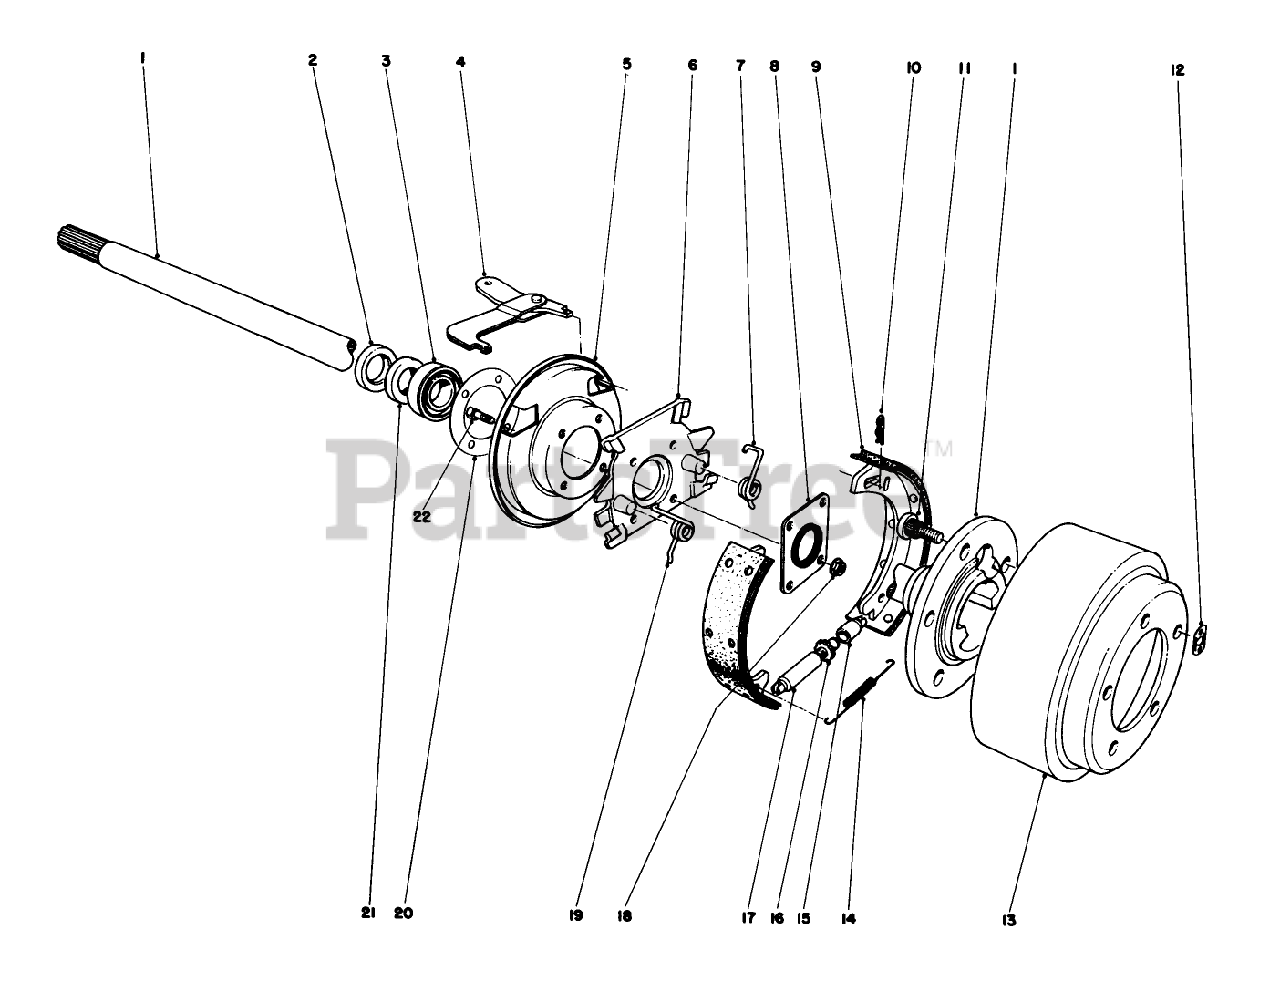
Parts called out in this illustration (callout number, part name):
1	SHAFT-AXLE, FLANGED
2	Oil Seal
3	BEARING ASM
4	STRUT AND LEVER ASM
5	SHIELD-DUST
6	SPIDER-TORQUE
7	SPRING-RETURN, RH
8	SEAL-GREASE
9	Assy.-Shoe & Lining
10	RETAINER-LEVER, BRAKE
11	STUD-DRIVE
12	CLIP-RETAINING
13	DRUM-BRAKE
14	SPRING-SCREW, ADJUSTING
15	SOCKET-SCREW, ADJUSTING
16	SCREW-ADJUSTING
17	NUT-PIVOT
18	Locknut
19	SPRING-RETURN, LH
20	Gasket Wheel Baaring
21	RING-RETAINING, WHEEL BEARING
22	Screw
